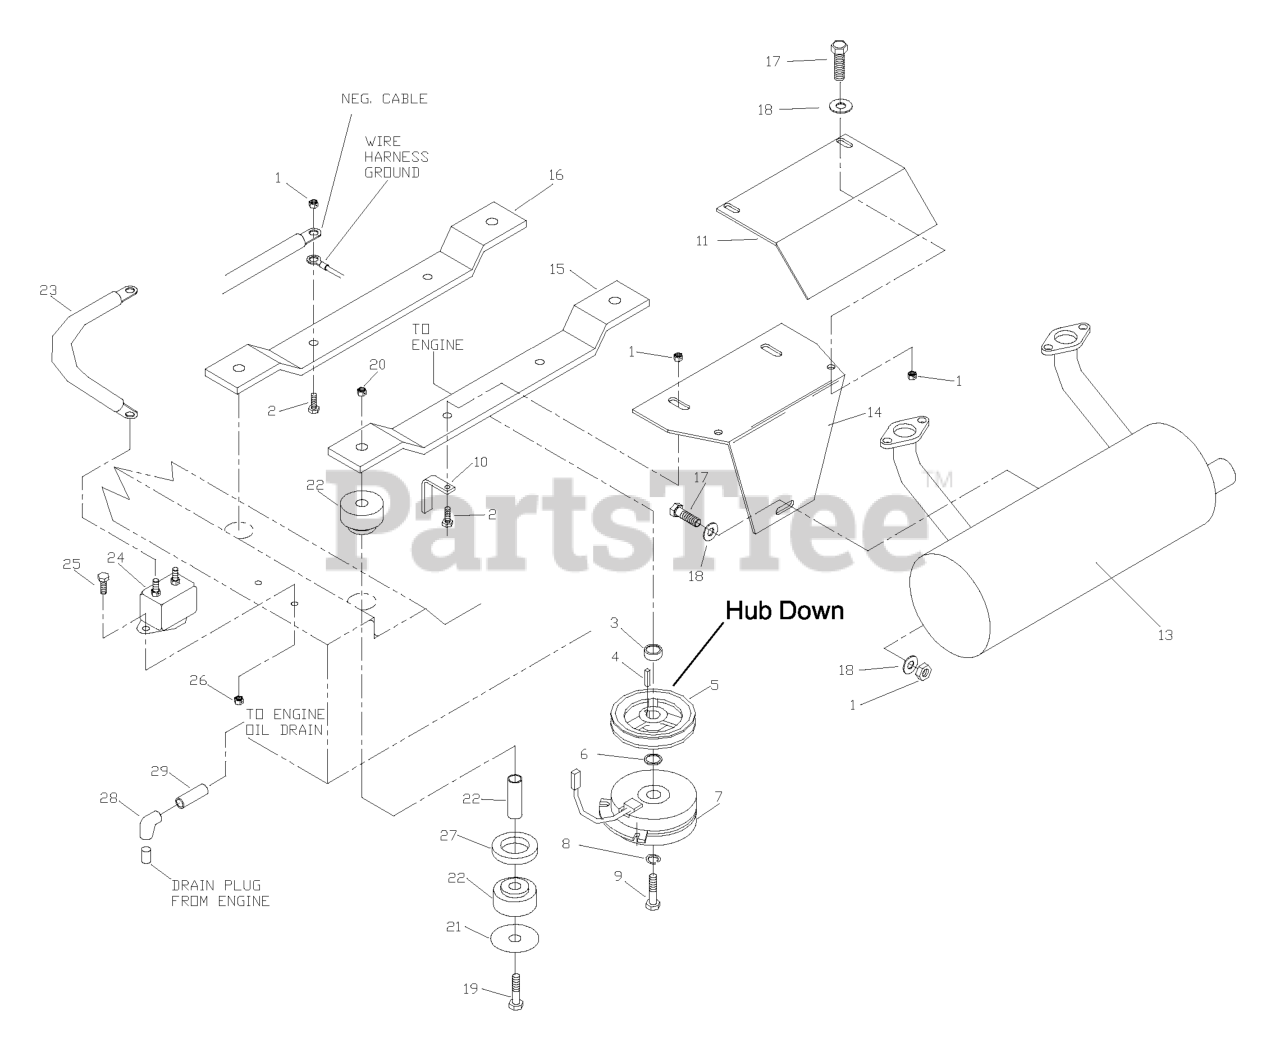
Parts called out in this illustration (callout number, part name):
1	NUT 5/16C CENTERLOCK
2	HCS 5/16C X 1 3/4
3	SPACER .70"
4	KEY 1/4 SQ X 1.0
6	SPACER .508"
8	7/16 LOCKWASHER
9	BOLT 7/16F X 2 1/2
10	CLUTCH TIE DOWN
11	MUFFLER GUARD, PAINT
12	KOH PIGTAIL
12	KAW PIGTAIL
13	MUFFLER KOH
13	MUFFLER KAW.
14	MUFFLER MT, PAINT
15	ENGINE MOUNT
16	ENGINE MOUNT
17	HCS 5/16C X 3/4
18	WASHER 5/16 FLAT
19	HCS 1/2C X 3 1/4
20	NUT 1/2-13 HEX NYLOC ZD
21	ISOLATOR WASHER
23	CABLE POSITIVE
25	HCS 1/4C X 5/8
26	NUT 1/4C CENTER LOCK
27	ISOLATOR SPACER
28	90 DEG.ELBOW 3/8NPT
29	PIPE 3/8 NPT 1-1/2
